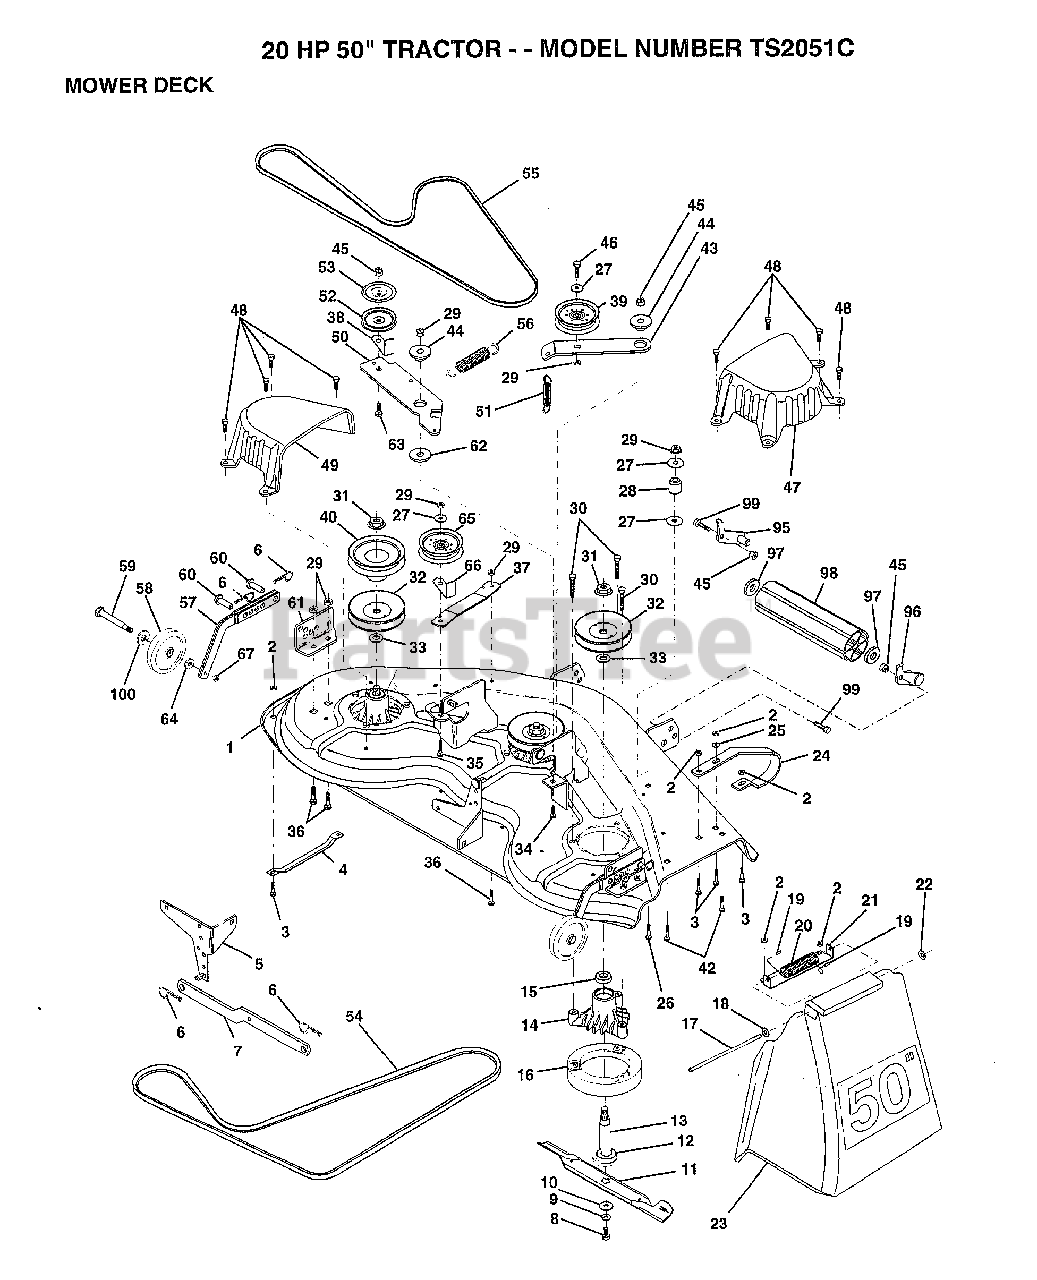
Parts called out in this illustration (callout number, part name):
1	DECK ASM MWR 50VT
2	NUT
4	RUNNER-LH M
5	BRKT.ASM.SW.44/50
8	BLADE BOLT
10	WASHER.HARD.BLADE
11	"BLADE.50"" HD"
12	BEARING.BALL
13	SHAFT.ASM.W/BRNG
14	HOUSING.MAND.44.V
15	BEARING
16	STRIPPER RND MWR
17	ROD-HINGE T
18	WASHER
19	CAP-SLEEVE LT
20	SPRING TORSION
21	BRKT DEFLECTOR
22	NUT PUSH M
23	DEFLECTOR
24	"RUNNER RH 50"" DK"
25	WASHER M
26	BOLT
27	WASHER
29	NUT
33	WASHER
34	BOLT.3/8-14X1.25
35	BOLT
36	BOLT D
37	STIFFENER.ARM.IDL
39	FLAT IDLER PULLEY
40	"PULLEY.DRIVEN.44"""
42	BOLT
43	"ARM.IDLER.SEC.44"""
44	SPACER RETAINER
47	"COVER.MAND.RH.44"""
48	SCREW.1/4-20X5/8
49	COVER.MANDREL.LH
50	ARM.IDLER.PRIMARY
51	"SPRING.SEC.44""VEN"
52	PULLEY.IDLER.VGRO
53	SHIELD.IDLER.44.V
54	BELT V PRIM 50
55	BELT.V.GDRIVE.95
56	SPRING.EXT.DECK.
57	BAR.ASM.GUAGE.WHL
58	WHEEL.GAGE.BLK.PL
59	BOLT M
60	PIN.CLEVIS
61	BRACKET.GUAGE.WHL
62	HARDENED WASHER
63	BOLT.3/8-16X1.50
64	WASHER
65	IDLER-FLAT T
67	LOCKNUT
97	WASHER
99	BOLT
100	WASHER
